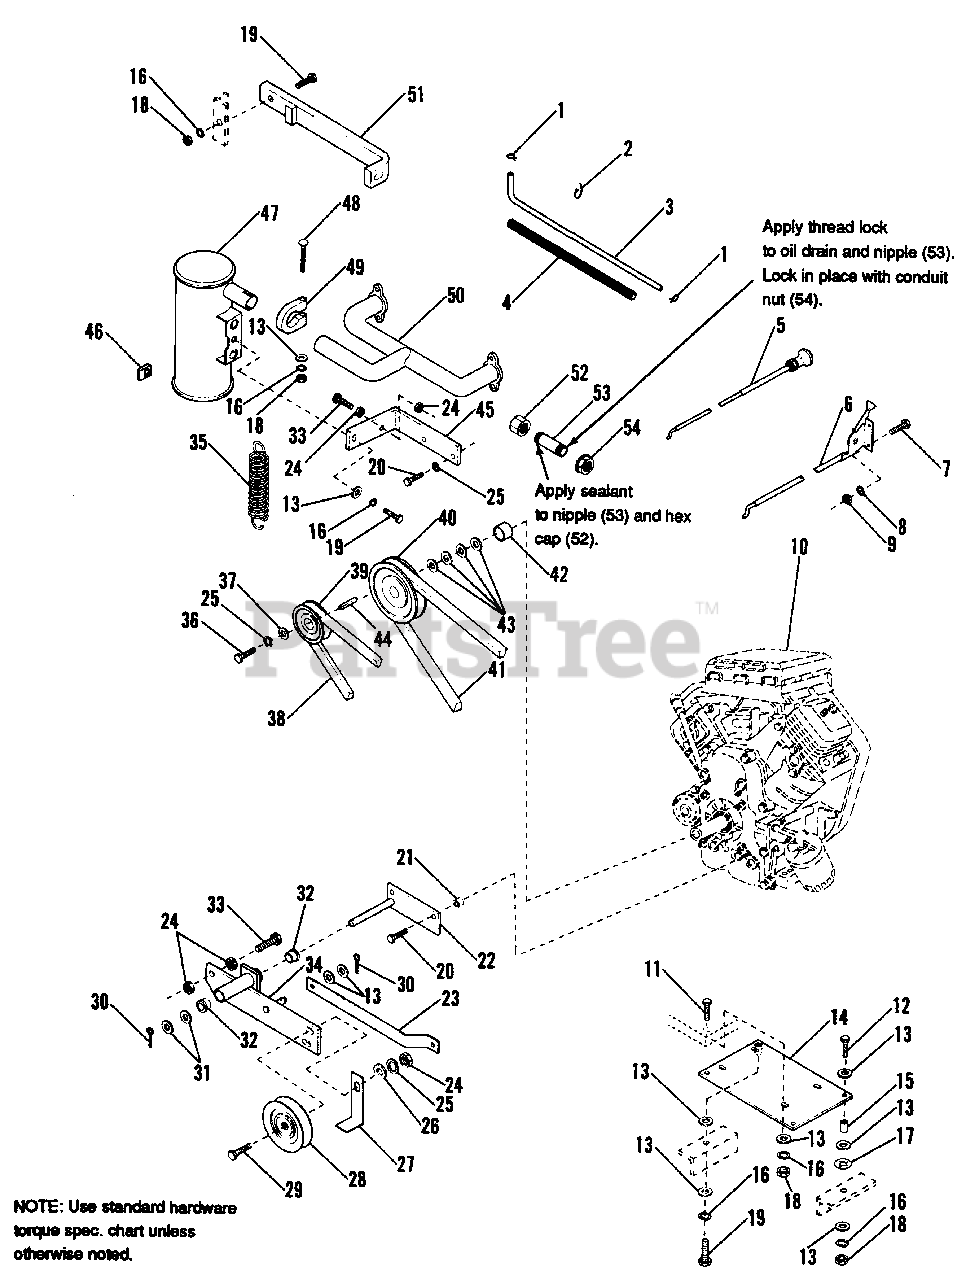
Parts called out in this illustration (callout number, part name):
1	CLAMP, Hose
3	HOSE, Fuel (Cut to 24" length)
4	TUBING, Flexible
5	CHOKE CABLE
6	THROTTLE CABLE
7	SCREW, Pan Head Phillips, #10-24 x 1
8	LOCKWASHER, Spring #10
9	NUT, Hex #10-24
10	ENGINE, 16 HP Briggs & Stratton
11	CAPSCREW, Hex 5/16-18 x 1-3/4
12	CAPSCREW, Hex Head 5/16-18 x 2 G5
13	WASHER, Plain
14	MOUNTING PLATE ASSY.
16	LOCKWASHER, Spring 5/16
18	NUT, Hex 5/16-18
19	CAPSCREW, Hex 5/16-18 x 3/4
20	CAPSCREW, Hex 3/8-16 x 1
22	IDLER PIVOT ASSY.
23	LINK, Clutch
24	NUT, Hex 3/8-16
25	LOCKWASHER, Spring 3/8
26	WASHER, Plain
27	RETAINER, Belt
28	V-PULLEY, Idler, PTO
29	CAPSCREW, Hex 3/8-16 x 1-1/2
31	WASHER, Plain
32	BEARING, Flanged
33	CAPSCREW, Hex 3/8-16 x 1-3/4
34	IDLER ARM ASSY.
36	CAPSCREW, Hex 3/8-24 x 1-1/2
37	WASHER, Plain
38	V-BELT, Traction
39	V-PULLEY, Traction
40	V-PULLEY, PTO
41	V-BELT, PTO
42	SPACER, Engine
43	WASHER, Plain
44	KEY, Square 1/4 x 1-3/4
45	SUPPORT, Muffler
46	PAL-NUT 5/16-18
47	MUFFLER ASSY.
48	CARRIAGE BOLT 5/16-18 x 2-3/4
49	CLAMP, Muffler
50	MANIFOLD ASSY., Exhaust
51	WIRE BRACKET ASSY.
52	CAP, Hex 3/8-18 NPT
53	NIPPLE, Pipe 3/8-18 x 1
54	NUT, Conduit 3/8-18
